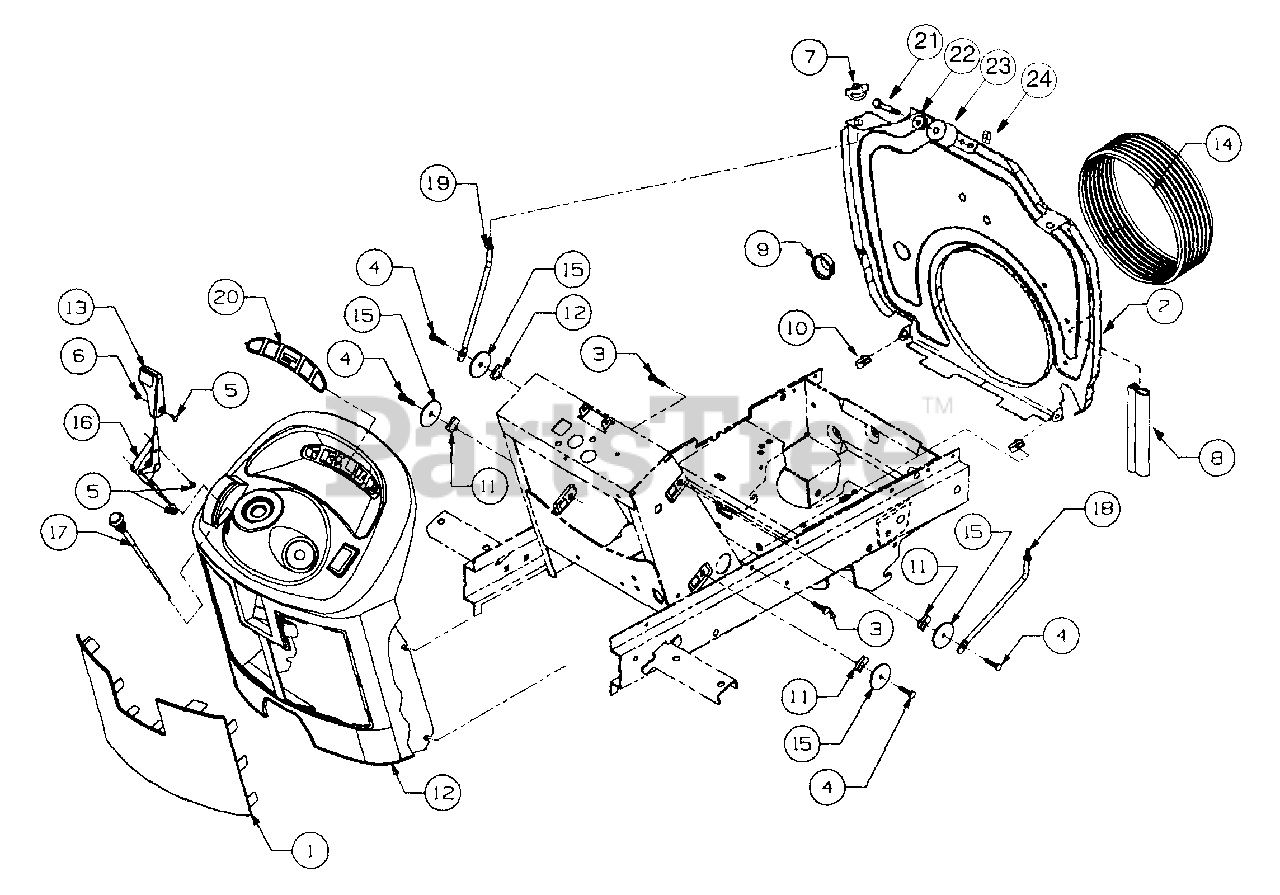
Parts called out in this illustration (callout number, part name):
2	Bulkhead, Lower
4	Screw, Hex Cap, 1/4-20 x 1.0
5	Screw, Cross Rec Truss Hd, #8-32 x .38
6	Nut, #8-32
7	Nut, Wing w/Bell Washer 1/4-20
8	Seal, Push-on Trim
9	Bushing, Snap, 7/8 ID
10	Nut, U-Type Speed, 1/4-20
11	Nut, U-Clip, 1/4-20
12	Panel, Dash
13	Knob, Throttle
14	Boot, Intake
15	Washer, Flat, .285 x 1.75 x 10
16	Control, Throttle
17	Control, Choke
18	Rod, RH Mounting
19	Rod, LH Mounting
20	Label, Dash
21	Screw, Hex Cap, 1/4-20 x 1.75 GR5
22	Washer, Flat, .283 x .75 x .030
23	Roller, Hood Latch
24	Nut, Hex Sems 1/4-20
